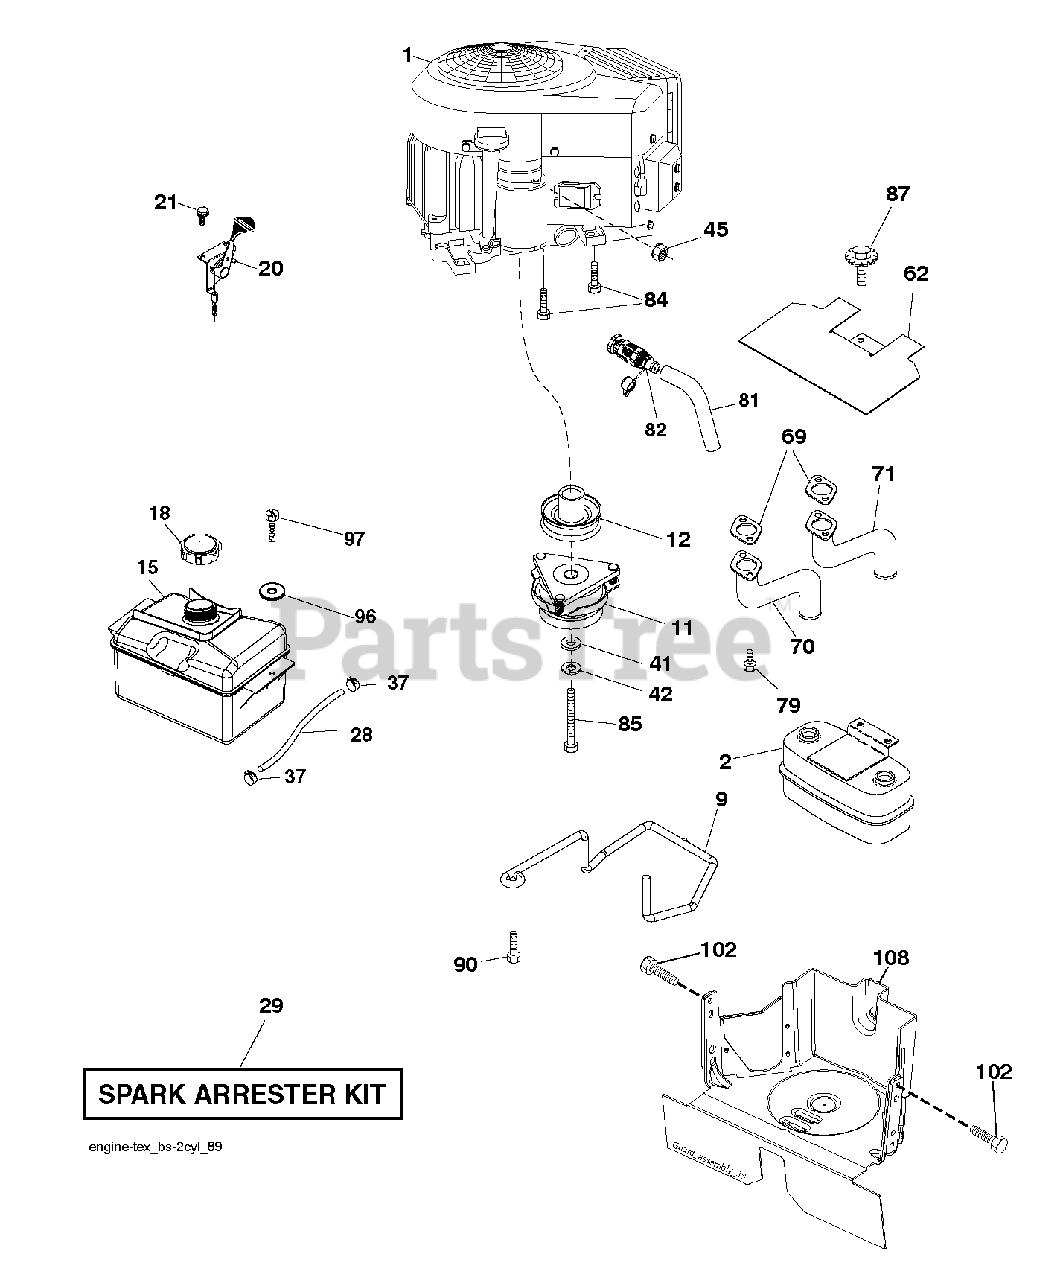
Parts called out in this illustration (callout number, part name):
2	MUFFLER.TWIN.CYL.LOW.TONE
9	KEEPER.BELT.ENGINE.4.2
11	CLUTCH.ELECTRIC.LT.48"*
12	PULLEY.ENGINE.TUFFTORQ
15	TANK.ASM.FRNT.2.GA.DAPCO.E10
18	CAP ASM.FUEL.2.25"FR.
20	CONTROL.TH/CK.COBRA.B&S.TWN.
21	SCREW.#10 X 0.750.BOS THREAD
29	ARRESTER SPARK (OPTIONAL)
42	LOCKWASHER
45	NUT
62	SHIELD.HEAT.MUFFLER
69	GASKET.MUFFLER
70	EXHAUST TUBE LH *SUBS/2*
71	EXHAUST TUBE RH
79	SCREW.SOCKET.HEAD.5/16-18
81	TUBE, DRAIN OIL ASM.
82	VALUE.OIL.DRAIN
85	BOLT HEX 7/16-20X4-1/4"
87	BOLT, 5/16-18 X 1 3/4
90	SCREW 3/8-16X1
97	SCREW HEXWSHR 1/4-20X3/4
102	SCREW 5/16-18X1
108	COVER PULLEY
